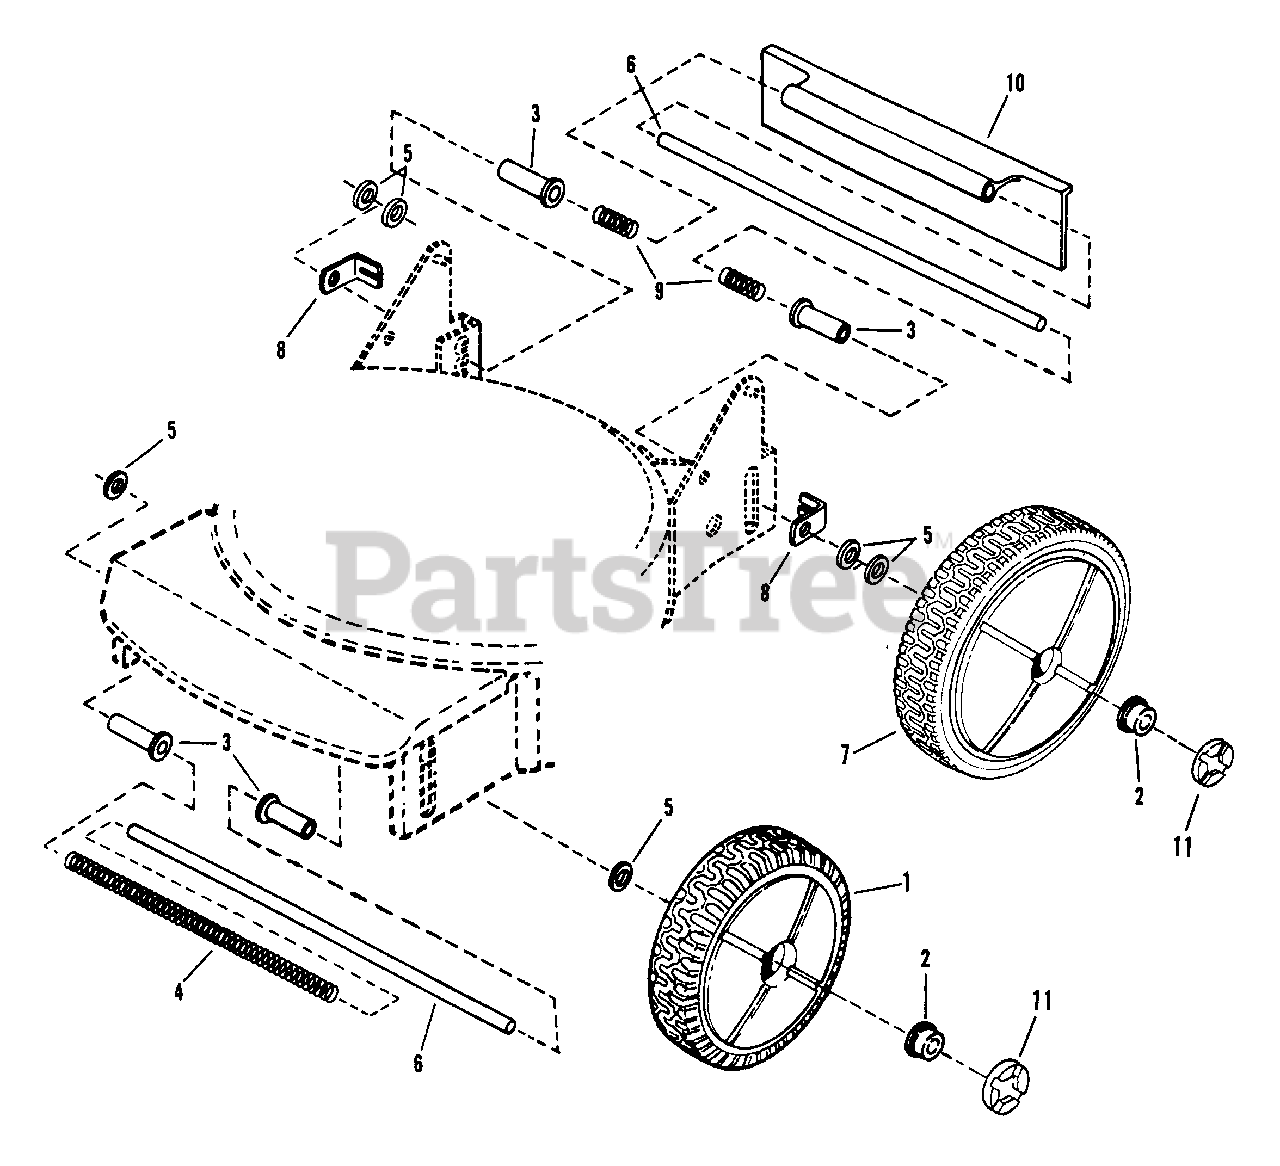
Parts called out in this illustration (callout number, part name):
1	WHEEL, Front 7 x 1.75
2	HUB-CAP, Wheel
3	BUSHING, Height Adjustment
4	SPRING, Front Axle
5	WASHER, 3/8" Flat
6	AXLE, 3/8 x 19-3/8"
7	WHEEL, Rear 8 x 2.00
8	CLIP, Rear Guard
9	SPRING, Rear Guard
10	GUARD, Rear Foot
11	PLUG, Wheel
